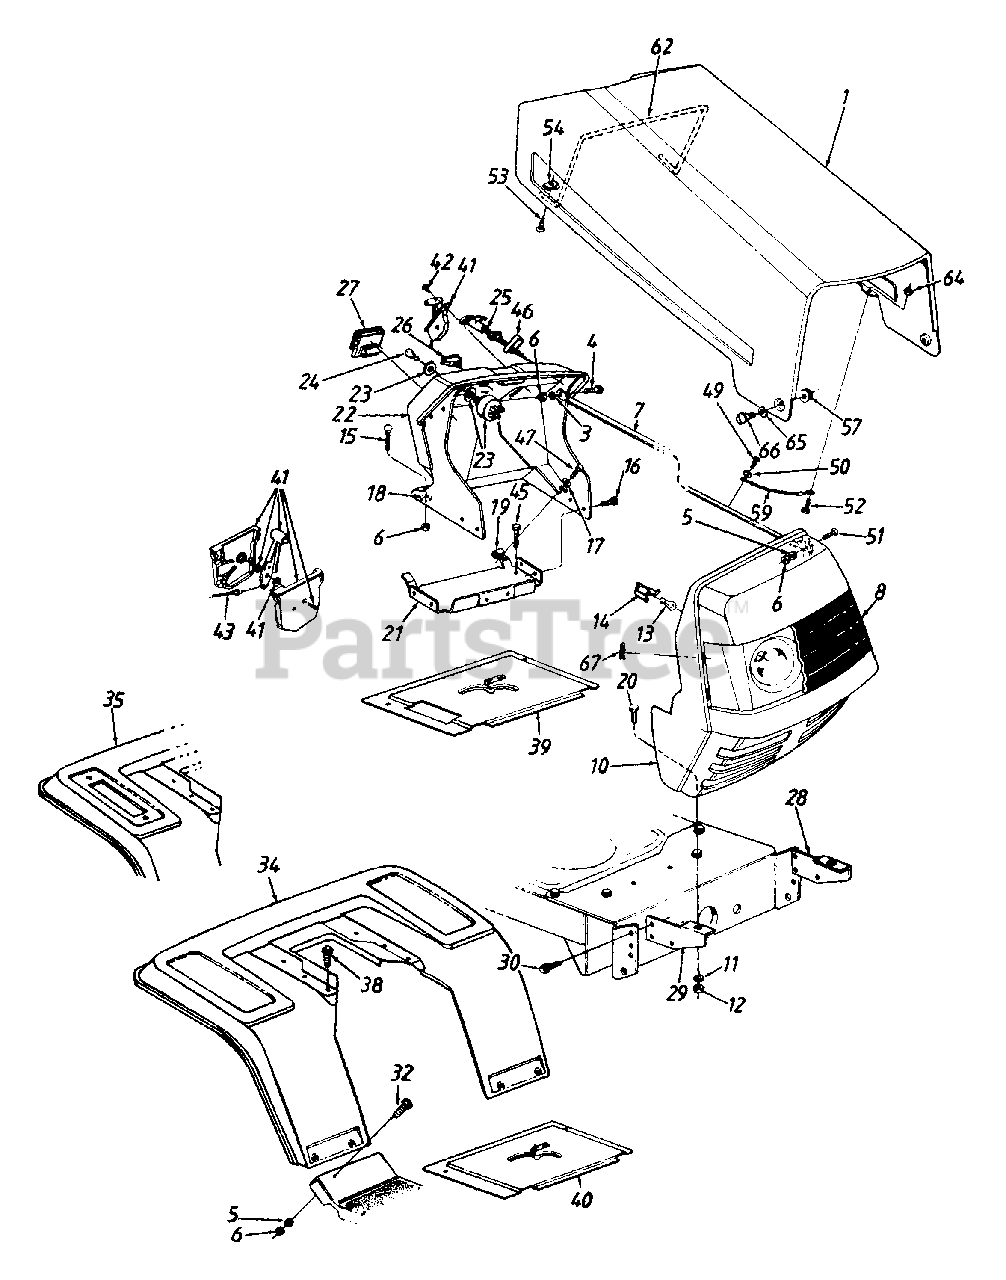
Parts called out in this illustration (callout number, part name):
3	Fl-Wash. .28" I.D. x .75" O.D.
4	Hex Bolt 1/4-20 x .62" Lg.
5	L-Wash. 1/4" I.D.
6	Hex Nut 1/4-20 Thd.
12	Hex Nut 5/16-18 Thd.
13	Lamp
14	Socket
15	Carriage Bolt 1/4-20 x .75" Lg.
16	Hex Wash. Hd. TT-Tap Scr. 1/4-20 x .5" Lg.
17	Fl-Wash. .281" I.D. x .73" O,D.
18	Bolt Retainer 1/4" I.D.
19	Speed Nut 1/4-20 Thd.
20	Hex Bolt 5/16-18 x .75" Lg.
21	Gas Tank Support Brkt.
22	Dash
23	Ignition Switch
24	Ignition Key
25	Choke Control 23" Lg.
26	Light Switch
27	Ammeter
28	Grille Mtg. Brkt. - L.H.
32	Truss Mach. Scr. 1/4-20 x .5" Lg.
38	Hex Wash. Hd. AB-Tap Scr. 5/16 x .75" Lg.
39	Shift Cover w/ Cutout
40	Shift Cover
41	Throttle Box Ass'y.
42	Truss Mach. AB-Tap Scr. #10 x .5" Lg.
43	Throttle Control Wire 18.5" Lg.
45	Hex Wash. Hd. B-Tap Scr. 5/16-18 x .5" Lg.
46	Choke Retainer
47	Hex TT-Tap Scr. 1/4-20 x .75" Lg.
49	Truss Mach. B-Tap Scr. #10 x .5" Lg.
50	Fl-Wash. .218" I.D. x .62"
51	Truss Mach. Scr. 1/4-20 x .75"
52	Truss Mach. Scr. #10-24 x .5" Lg.
53	Pan Hd. Scr. #10-24 x .75"
54	Speed Nut
57	Lock Nut 1/4-28 Thd.
59	Hood Stop
62	Hood Spring
64	Hex Sems Nut #10-24 Thd.
65	Spr. Wash. .39" I.D. x .62" O.D.
66	Shld. Bolt
67	Hairpin Clip 5/16" Dia.
